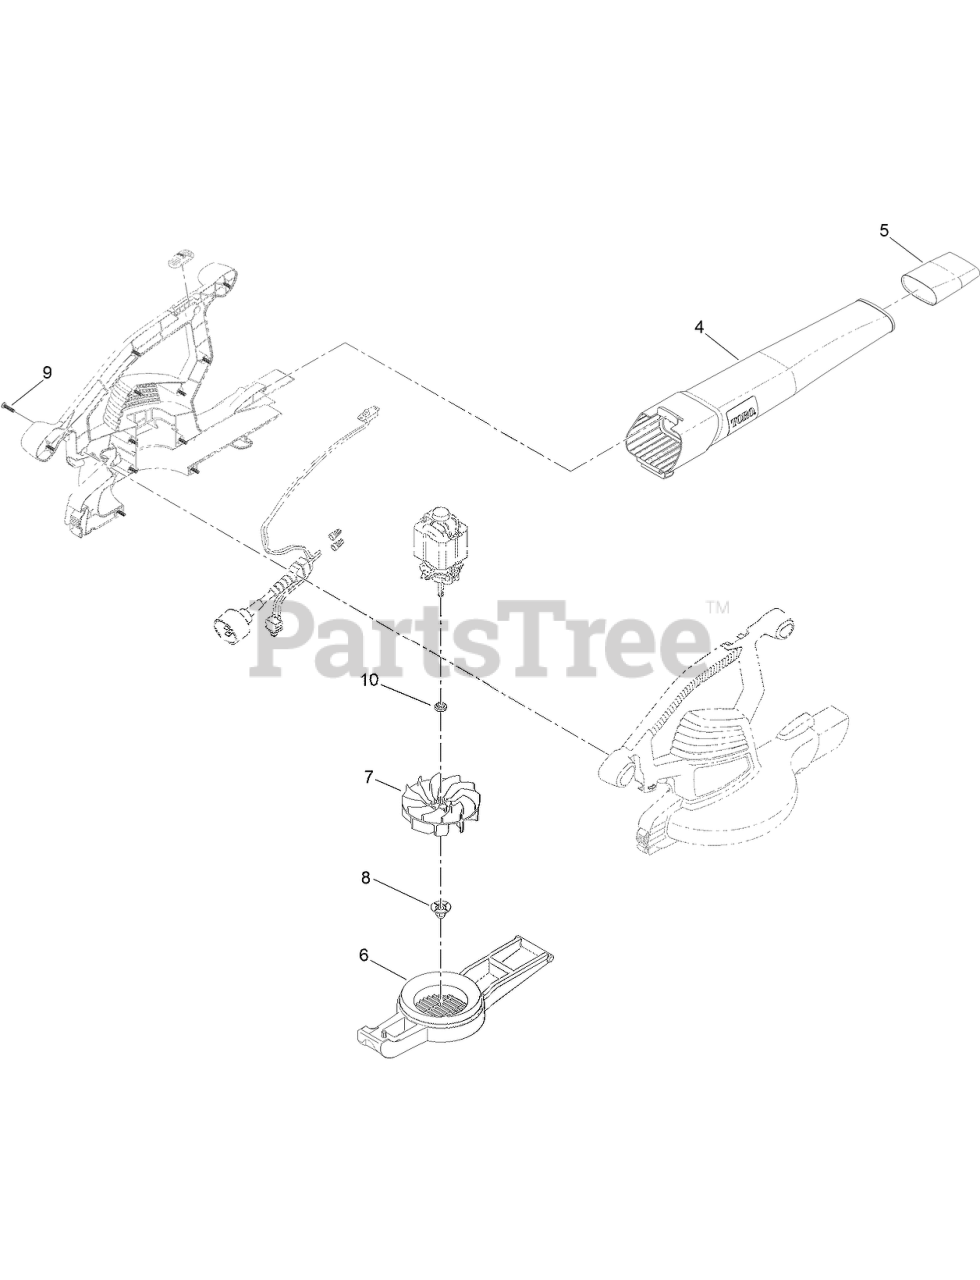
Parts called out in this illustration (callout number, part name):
4	TUBE-BLOWER
5	TUBE-INSERT, SUPER
6	COVER-INLET
7	IMPELLER
8	NUT-IMPELLER
9	SCREW-PPH
10	BUSHING-MOTOR
